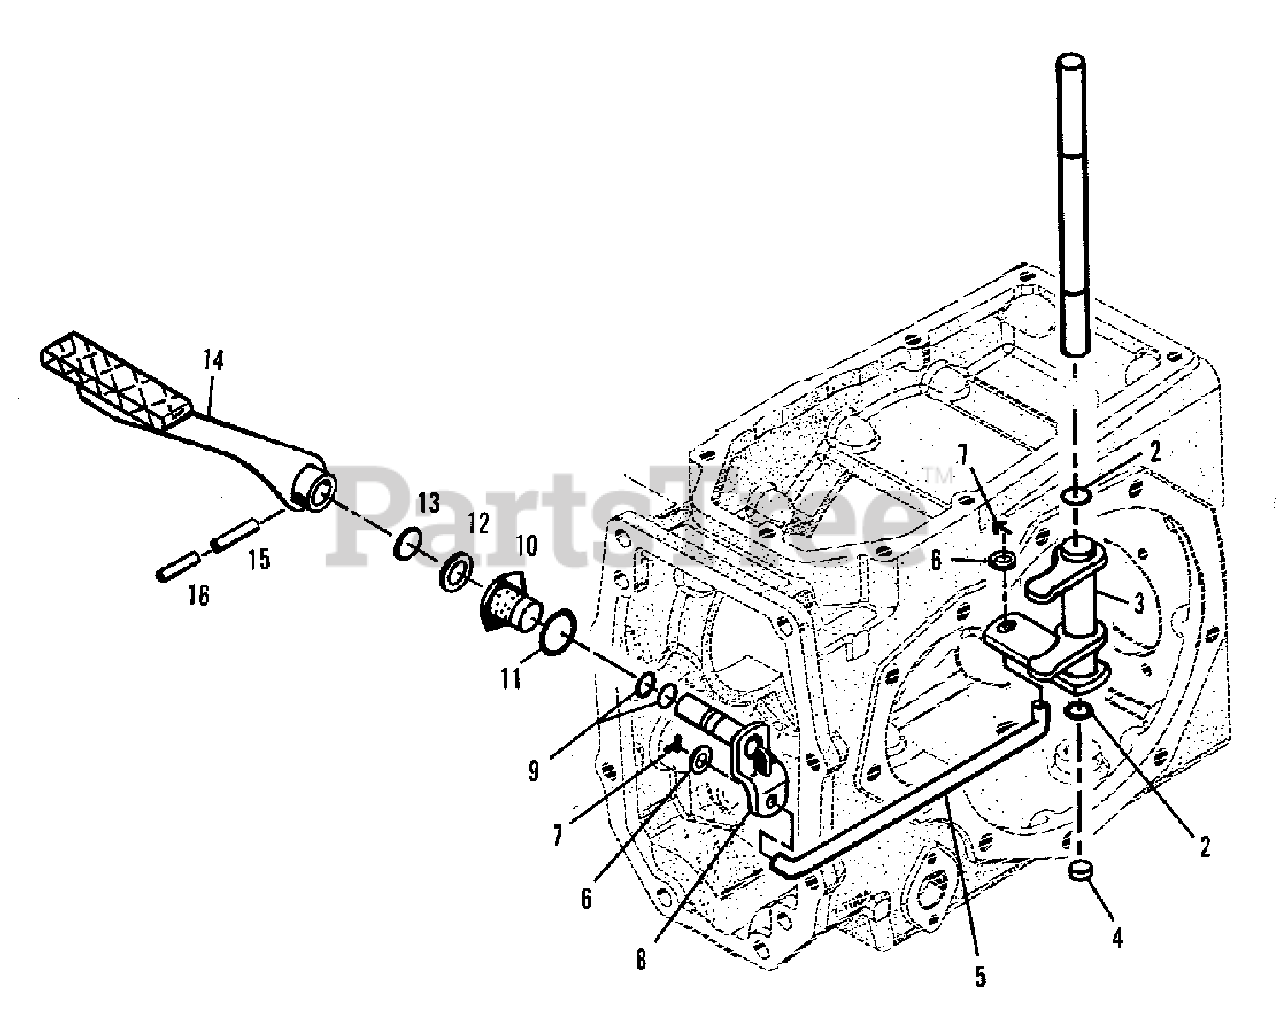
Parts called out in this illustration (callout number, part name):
1	SHAFT, differential lock
2	RING, M18, snap-external
3	LEVER, shift
5	Rod, shift
7	PIN, cotter
8	LEVER, control
10	GUIDE, control lever
12	WASHER, thrust
13	RING, M20, snap-external
15	PIN, M8 x 32, lock
16	PIN, M5 x 32, lock
